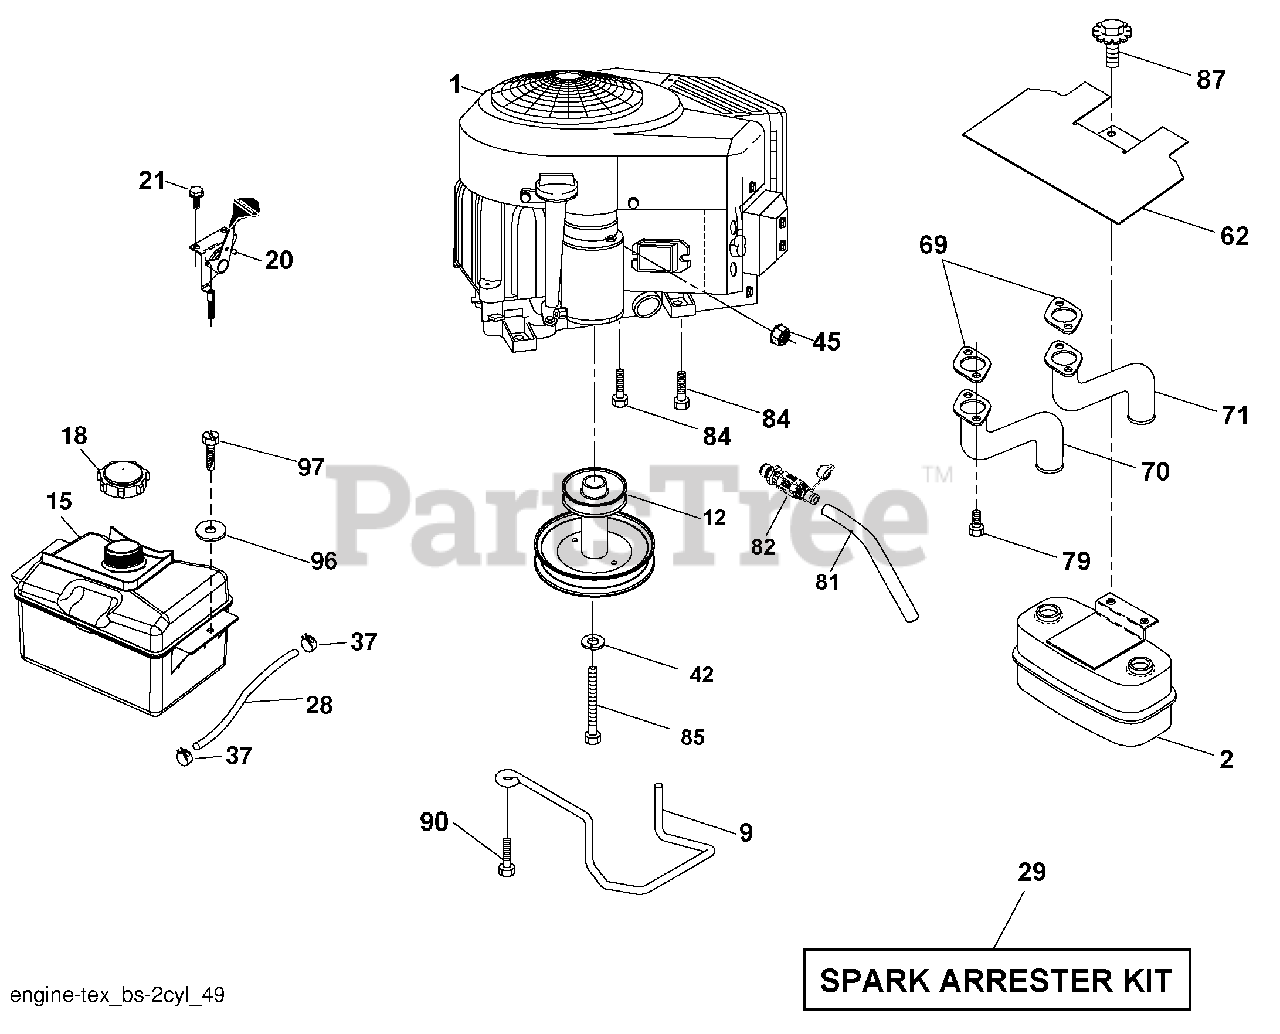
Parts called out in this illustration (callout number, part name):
2	Muffler
9	Keeper Belt Engine
12	Pulley Engine
15	Tank Fuel
18	Cap Fuel
20	Control Throttle/Choke
21	Screw #10 x 0.750 BOS Thread
28	Fuel Line
29	Spark Arrester Kit
37	Clamp Hose
42	Washer Lock 7/16
45	Nut Keps Hex 1/4-20 unc
62	Shield Heat Muffler
69	Gasket
70	Exhaust Tube LH
71	Exhaust Tube RH
79	Screw Socket HD 5/16-18 x 1
81	Tube Drain Oil Easy
82	Valve Drain Oil
84	Screw 3/8-16 x 1-1/4
85	Bolt 7/16-20 x 4 x Gr. 5-1.5
87	Bolt 5/16-18 unc x 3/4
90	Screw 3/8-16 x 1
96	Washer 9/32 x 7/8 x 16 Ga.
97	Screw 1/4-20 x 3/4
